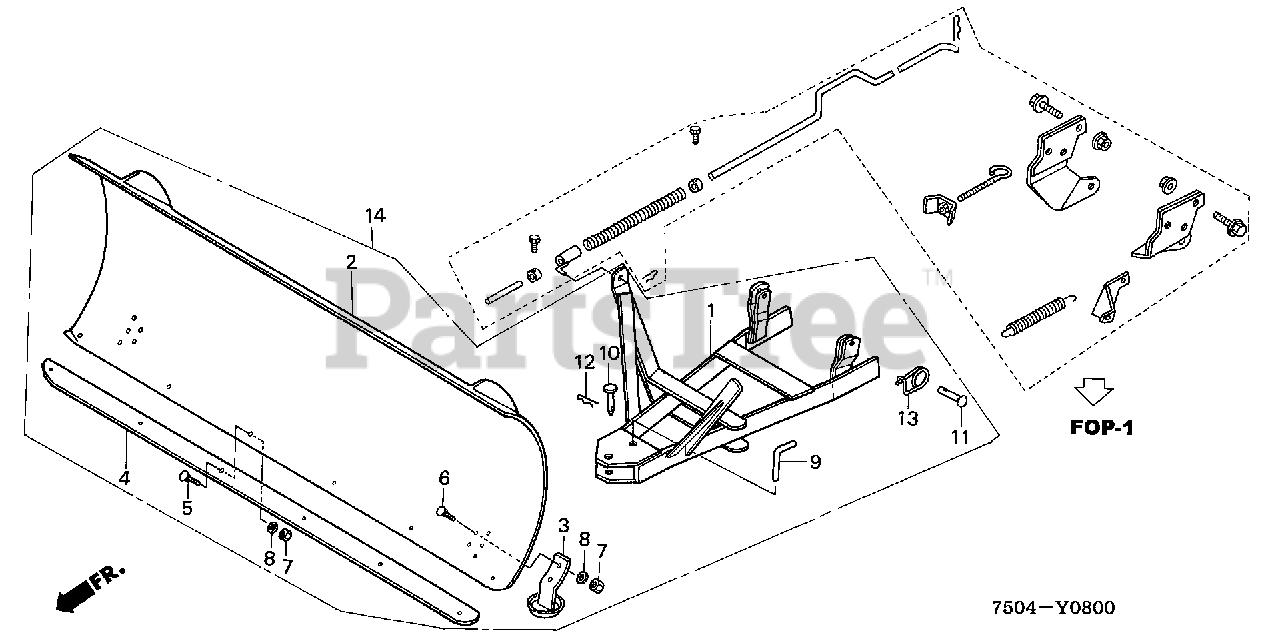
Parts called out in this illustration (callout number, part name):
2	BLADE ASSY. (42")
3	SHOE ASSY.
4	PLATE, WEAR
5	BOLT (3/8-16X3/4)
6	BOLT (3/8-16X1)
7	NUT, HEX. (3/8-16)
8	WASHER, LOCK (0.375)
9	PIN, PIVOT
11	PIN (10X31)
12	CLIP, SPRING
13	PIN, LOCK (10MM)
14	DOZER KIT, SNOW
